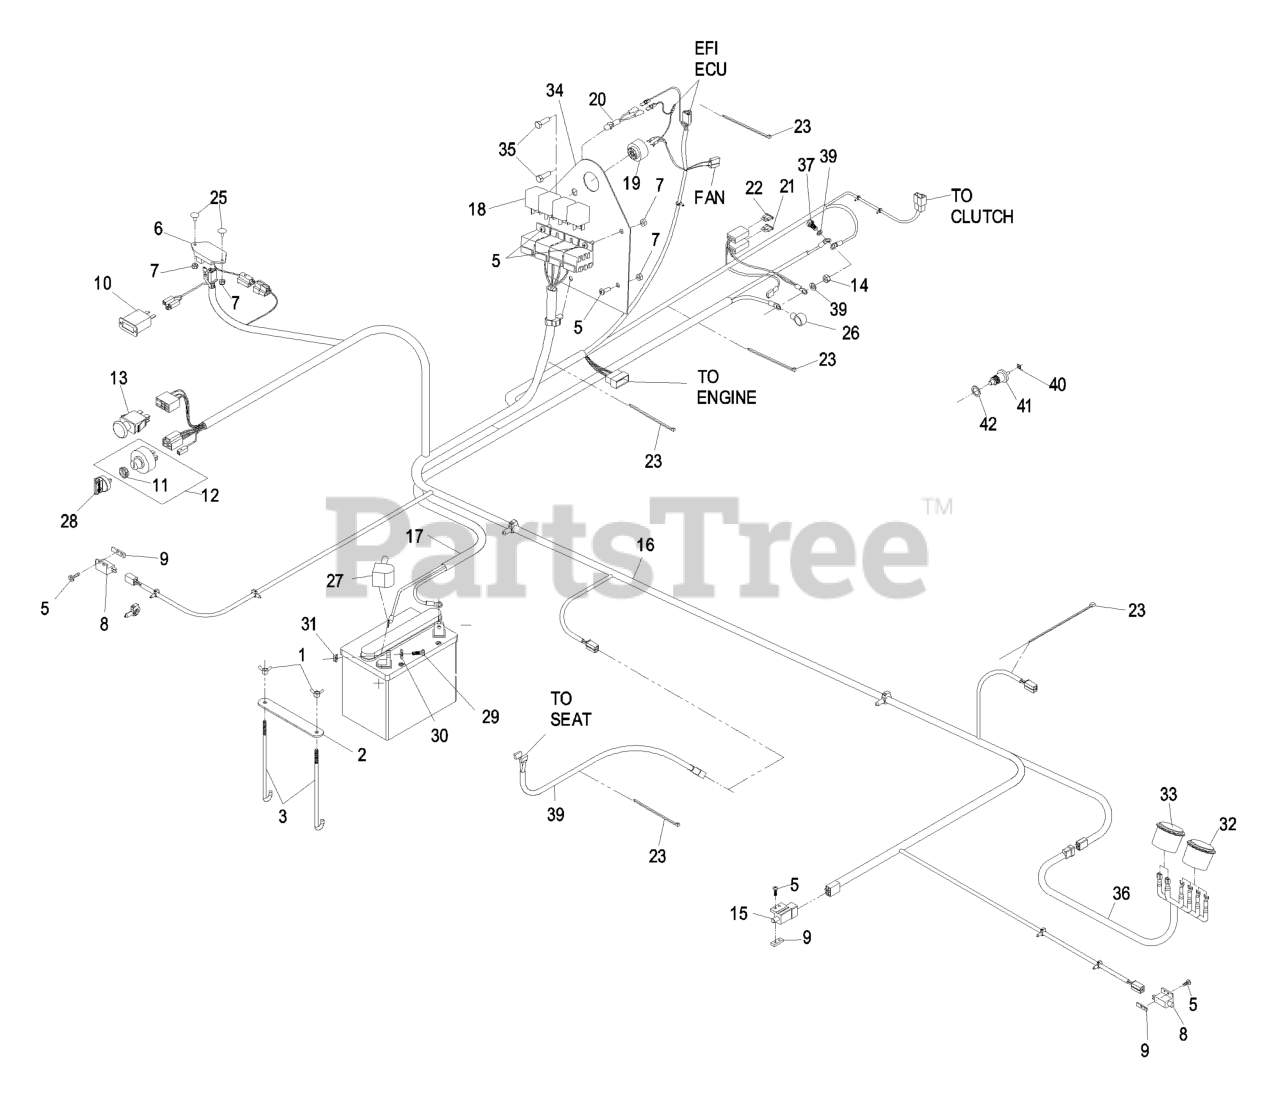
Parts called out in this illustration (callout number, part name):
1	WINGNUT
2	STRAP-HOLDDOWN, BATTERY
3	BOLT-HOLDDOWN
4	Battery, Wet
5	SCREW-PPH
6	MODULE-DELAY, SEAT
7	NUT-LOCK, NI
8	SWITCH-OPEN, NORMALLY
9	PLATE-TAPPED
10	METER-HOUR
11	NUT-SWITCH, IGNITION
12	ASM,SWITCH W/NUT
13	SWITCH-PTO
14	Nut, Hex M8-1.25
16	HARNESS, WIRE LZ 29 LKA
17	ASM, BATTERY CABLE
19	ALARM-TONE, DUAL
20	INDICATOR-LED, RED
21	FUSE-BLADE TYPE, 30 AMP
22	FUSE-BLADE TYPE, 20 AMP
23	TIE-PLASTIC
25	BOLT-CARR
26	INSULATOR-SOLENOID
28	KEY-IGNITION
29	SCREW-HH
30	WASHER-FLAT
32	GAUGE,TEMP W/ ALERT
33	GAUGE-VOLTMETER
34	ASM,ELECT.PNL W/ DECALS
35	SCREW-HWHTF
36	HARNESS,GAGE
37	SCREW-HH
38	WASHER-PLAIN
39	HARNESS-WIRING, SEAT
41	SENDER-TEMPERATURE
42	WASHER-ALUMINUM
